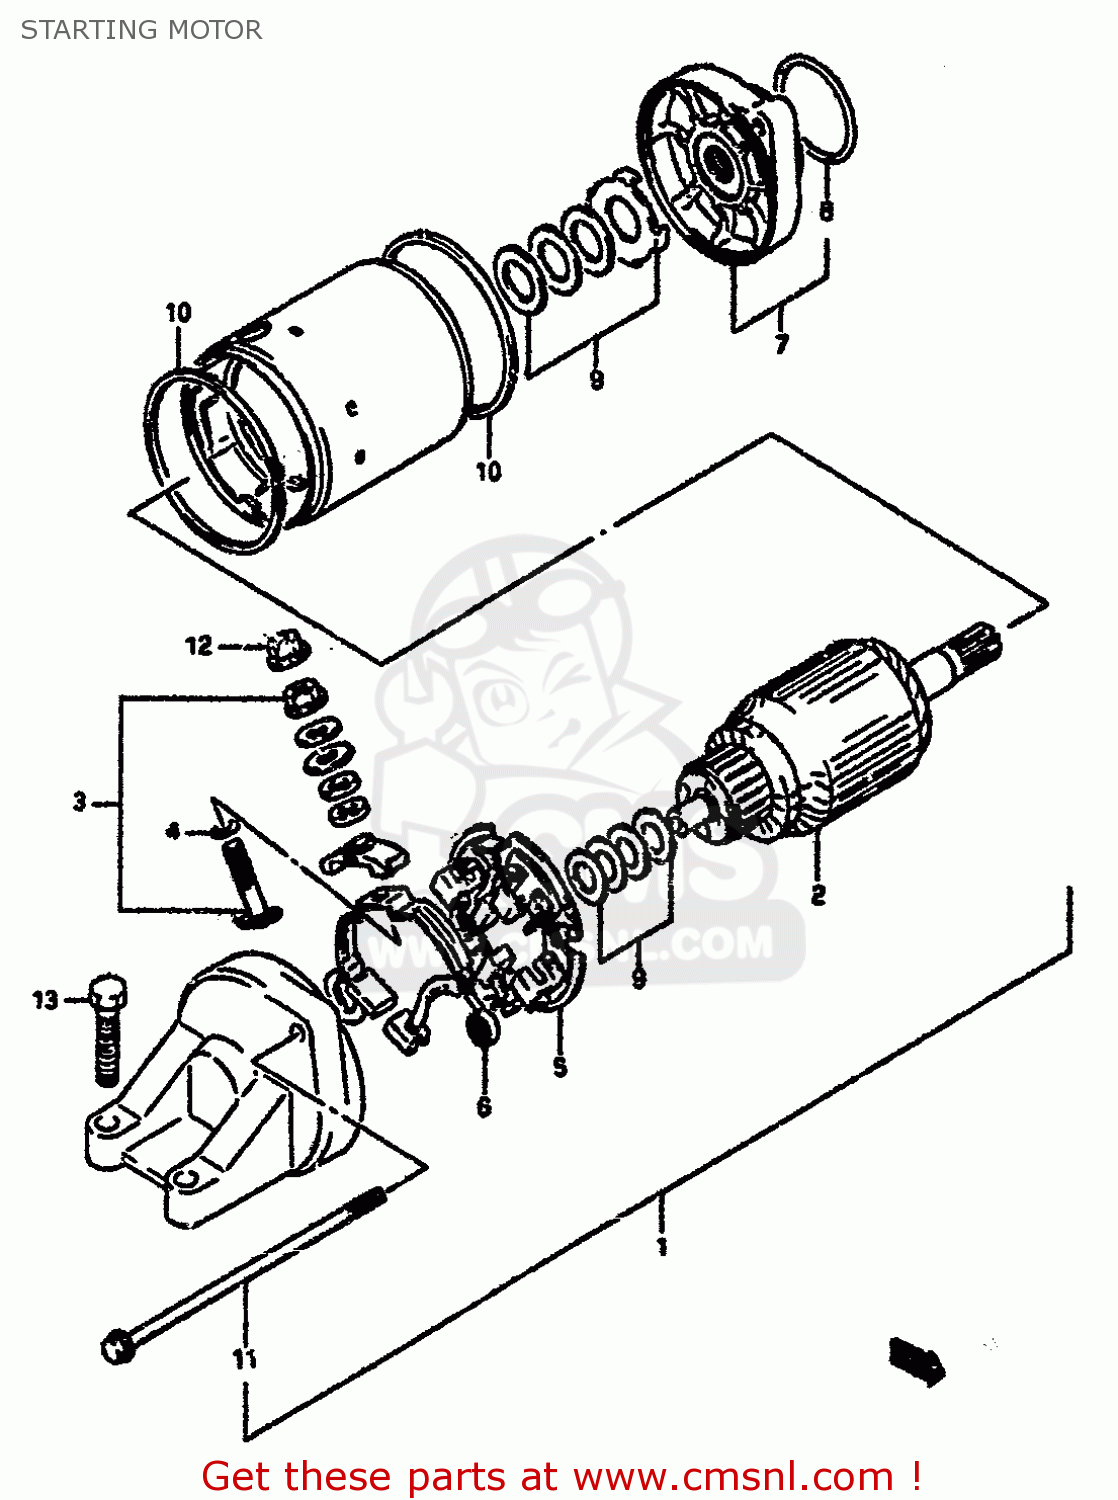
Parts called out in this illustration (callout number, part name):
1	MOTOR ASSEMBLY,STARTING
2	ARMATURE
3	TERMINAL SET,BRUSH
4	O RING
5	HOLDER SET,BRUSH
6	SPRING,BRUSH
7	BRACKET
8	O-RING
9	SHIM SET,STARTING MOTOR
10	O RING
11	BOLT
12	NUT
13	SCREW (6X25)
